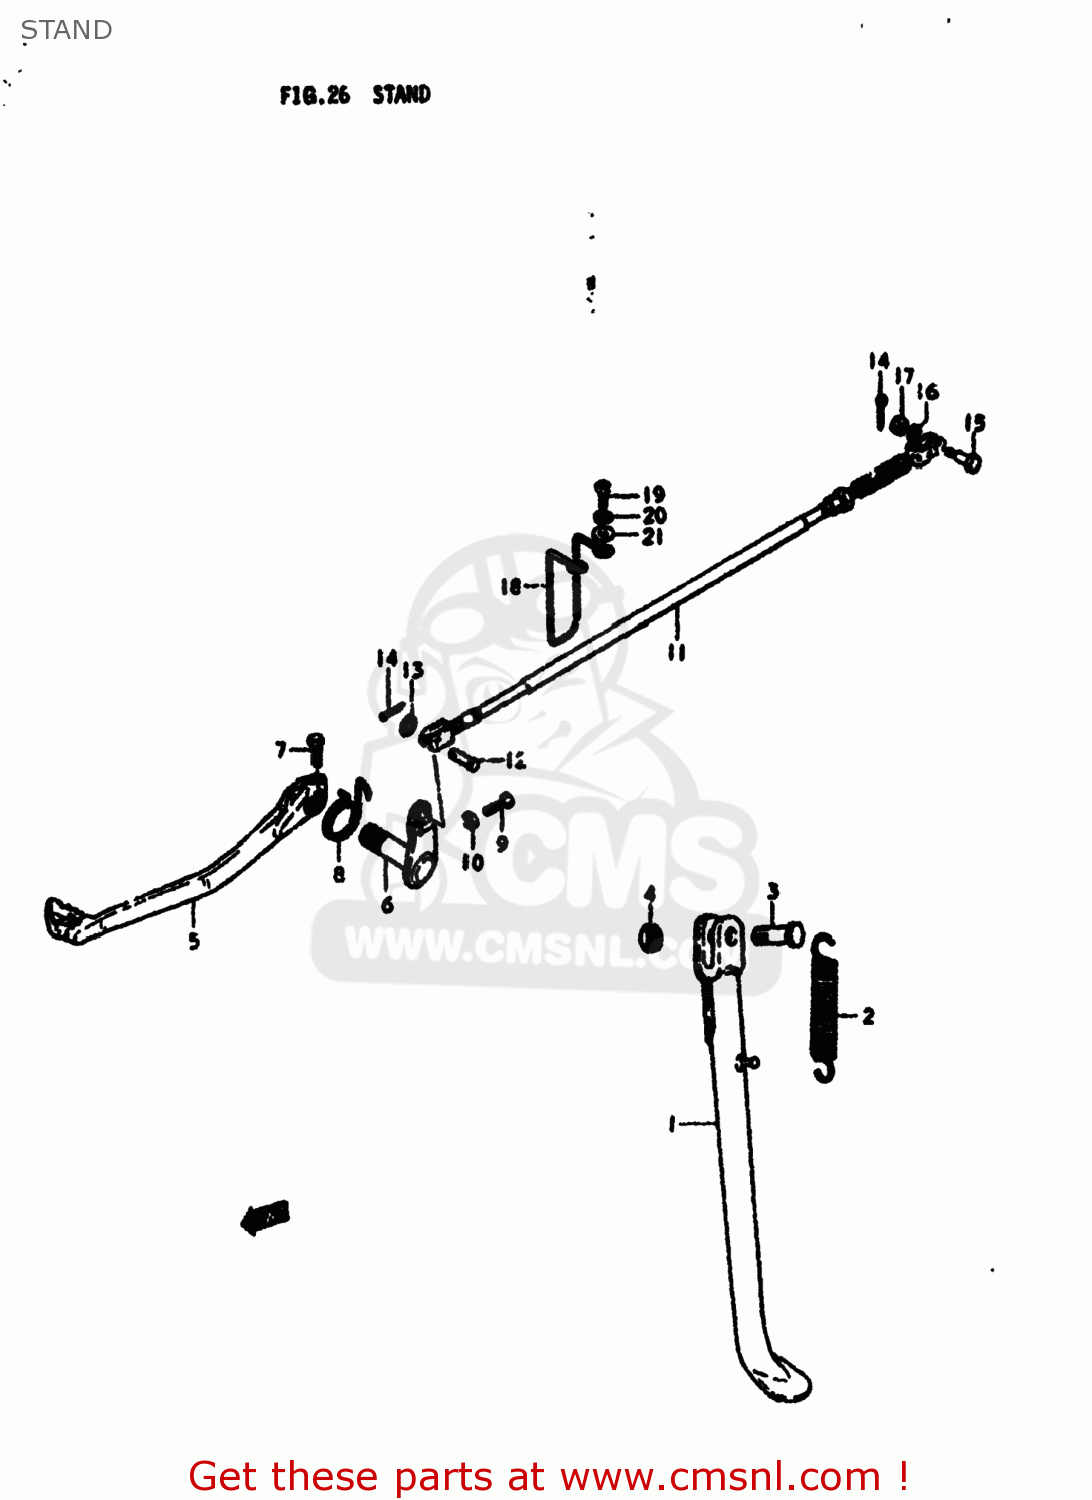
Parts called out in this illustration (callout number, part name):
1	STAND,SIDE
2	SPRING
3	BOLT(10X30)
4	NUT
5	PEDAL,BRAKE
6	ARM,BRAKE PEDAL
7	BOLT
8	SPRING
9	BOLT(6X23)
10	NUT
11	CABLE,RR BRAKE
12	PIN(L:17.5)
13	WASHER
14	PIN
15	BOLT
16	SHIM (8.5X16,5X0.8)
17	NUT
18	GUIDE,BRAKE CABLE
19	BOLT
20	LOCK WASHER
21	WASHER
